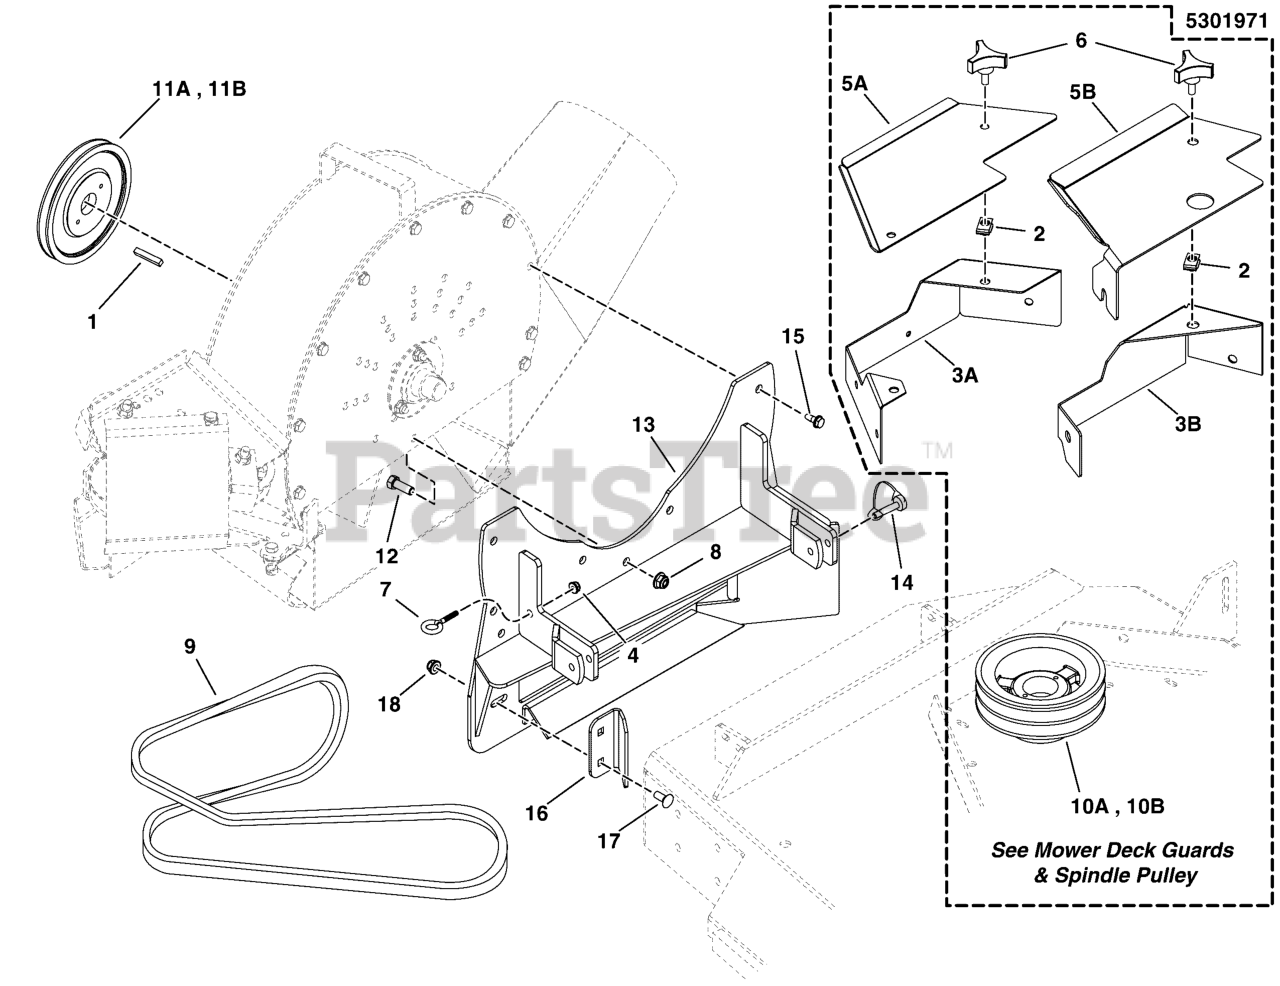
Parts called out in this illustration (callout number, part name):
1	KEY 1/4 SQ X 1 1/2 LONG
2	BODY CLIP, 5/16-18-7GA MATERIAL
4	NUT, 1/4-20 Hex Nylock Flange
6	KNOB, PLASTIC, 5/16-18 X 3/4"
7	EYE BOLT, 1/4-20 X 2.5, 1THRD, .5EYE,CZ
8	NUT, 3/8 - 16 HEX NYLOCK FLANGE
9	BELT, A-SEC, 92.00EL, ARAMID, WRPD
12	BOLT, 3/8-16 X 1" GD5 CZ
13	WELD, ADAPTER, 52ICD, FVAC BLK (5302764)
14	SNAPPERPIN, 5/16 X 2
15	BOLT, 5/16-18 X 5/8" Self Lock
16	BRACKET,DEFLECTOR PLATE,52iCD 2011 - BLK
17	BOLT, 5/16-18 X 3/4, CARRIAGE, GD5, CZ
18	NUT, 5/16-18 HEX NYLOCK FLANGE NUT
